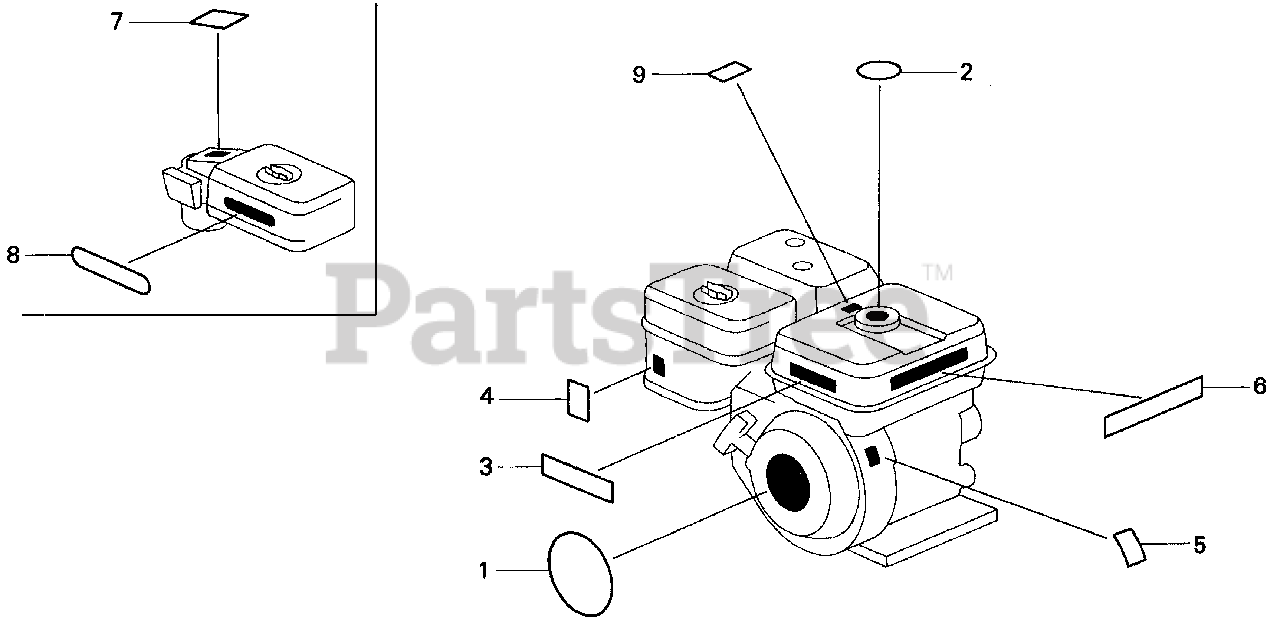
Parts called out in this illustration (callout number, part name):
1	EMBLEM (INTERNAL)
1	EMBLEM
3	LABEL, CAUTION
4	MARK, CHOKE
6	MARK, OIL ALERT (GERMAN)
6	MARK, OIL ALERT (FRENCH)
6	MARK, OIL ALERT (E)
